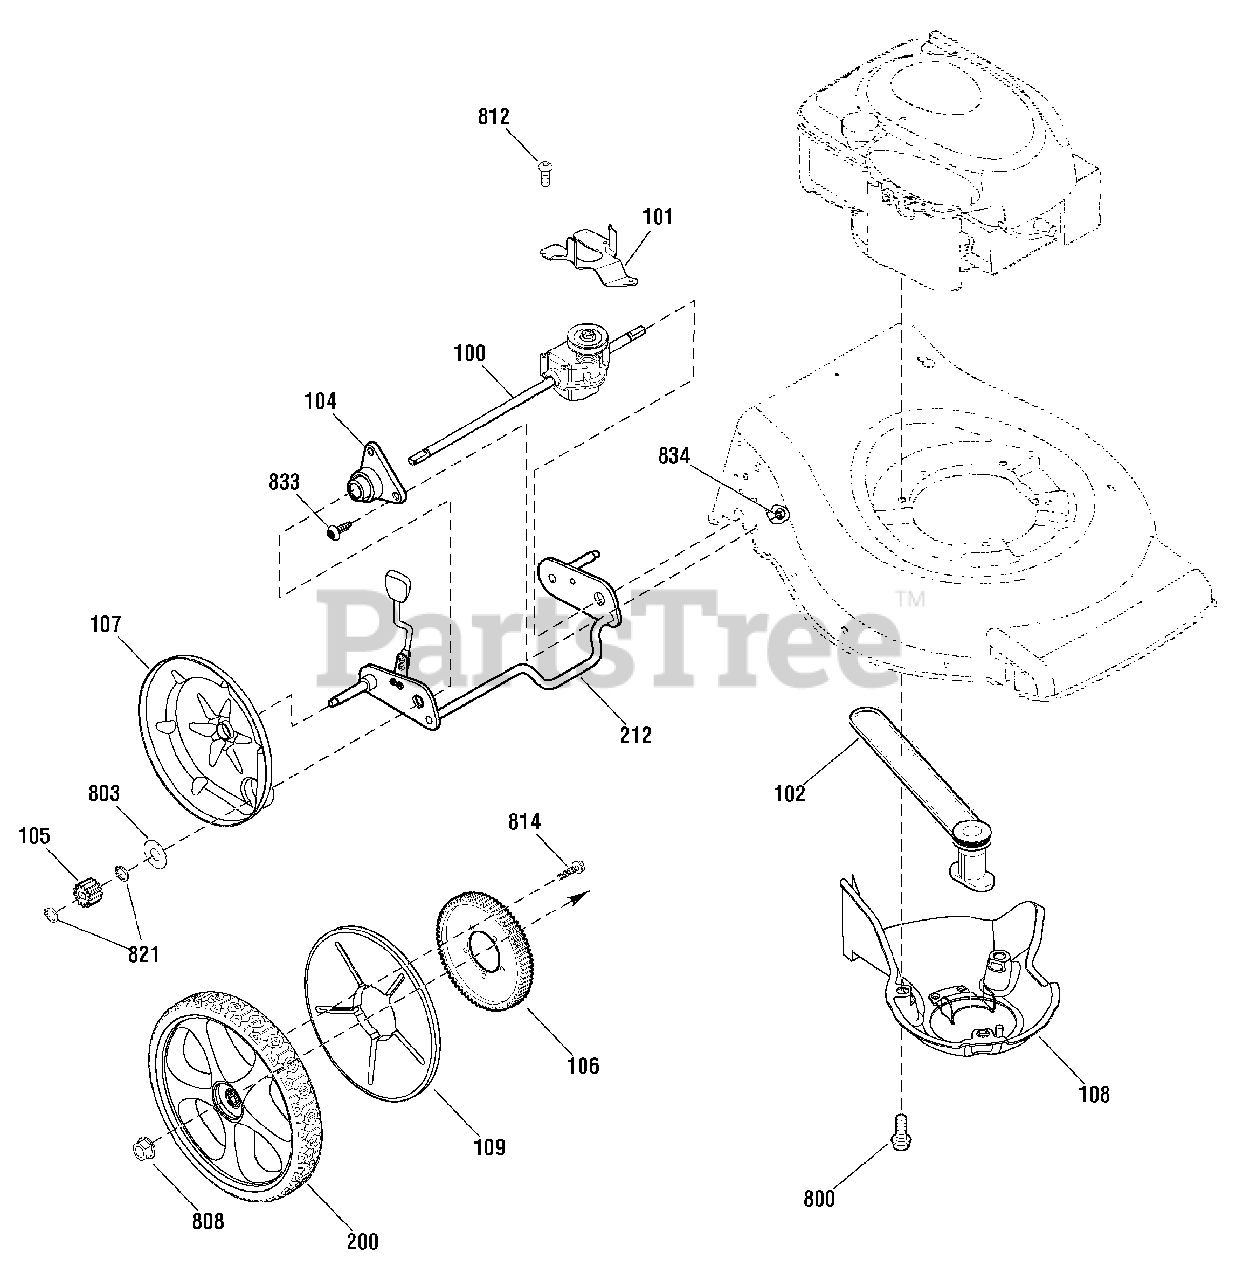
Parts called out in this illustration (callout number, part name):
100	TRANSMISSION
101	BELT GUIDE, Transmission
102	V-BELT
104	SLEEVE ASSEMBLY, Rear Axle
105	GEAR, Pinion
106	GEAR, Drive
107	DUST COVER
108	BELT COVER ASSEMBLY
109	COVER, Wheel
200	WHEEL, Rear
212	CROSSBAR ASSEMBLY, Rear
800	SCREW, Hex Head, 3/8-16 x 1
803	WASHER, Thrust
808	NUT, Flange, 3/8-16
812	SCREW, #10 x 1
814	SCREW, 1/4-15 x 3/4
821	RING, External Retaining
833	SCREW, Torx, 1/4-20 x 5/8
834	NUT, Flange Lock, 1/4-20
